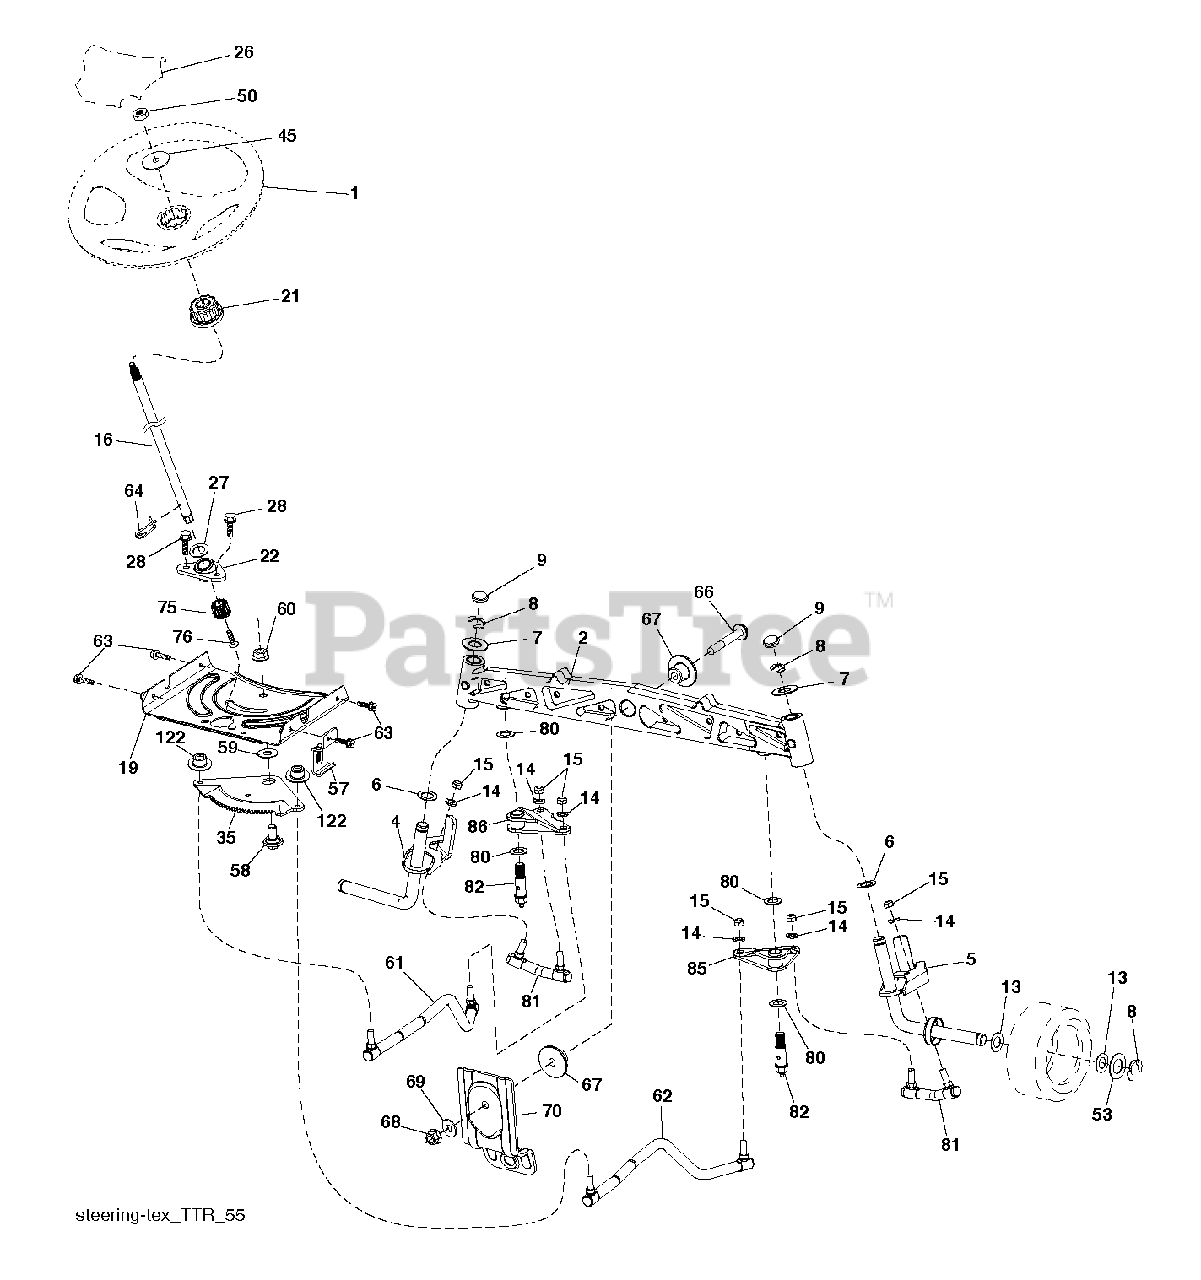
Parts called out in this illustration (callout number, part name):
1	WHEEL.STEER.HUSQ.SR.498.OVMLD
2	RP SUBASM.AXLE.CAST.NZTR.
4	SPINDLE WELDMENT.SPINDLE.LH.15
5	SPINDLE WELDMENT.SPINDLE.RH.15
6	THRUST WASHER
9	CAP.SPINDLE.BLACK
14	WASHER, LOCK 3/8
15	NUT CROWNLOCK 3/8-24
16	SHAFT.STEER.2HIGH.SPLND.PLATED
19	PLATE.STEER.DDL.NLT/NG
21	ADAPTER.WHEEL.STEER.SPLND.ALUM
22	BEARING.SUBASM.SHAFT.STEER.LOW
26	INSERT.CAP.WHL.STRG.HUSQ.PREM
28	SCREW, 3/8-16X3/4
35	GEAR GEAR.SECTOR.TEX.NZTR
45	WASHER.3/8ID.2-3/8OD.12GA.PLTD
50	NUT LOCK FLG 3/8-16 UNC
53	WASHER.HARDENED
57	BRKT.UPSTOP.GT/LT.TEX
58	BOLT.SHOULDER.SECTOR.P
59	WASHER.THURST.SECTOR.S
60	NUT FLANGE LOCK 5/8-11
61	LINK SUBASM.LINK.DRAG.LH.NZTR
62	TUBE TUBE
63	SCREW
64	RETAINER.CLIP.SPRING.S
66	BOLT HEX FGHD 7/16-14 X 3 SERR
67	BUSHING.PM.FRONT AXLE
68	NUT.LOCK.FLANGE.7/16
69	WASHER.1.5X.505X.118
70	BRACKET.FRT.DECK.SUSP.RR.MT431
75	PINION.ZINC PLATED
76	SCREW HEAD SOCKET LRVB
80	THRUST WASHER
81	LINK SUBASM.LINK.CROSS.NZTR
82	SUBASM;PIVOT;BOLT;NZTR
85	PIVOT SUBASM.PIVOT.RH.NZTR
86	PIVOT SUBASM.PIVOT.LH.NZTR
122	CAP.GEAR.SECTOR.TEX
